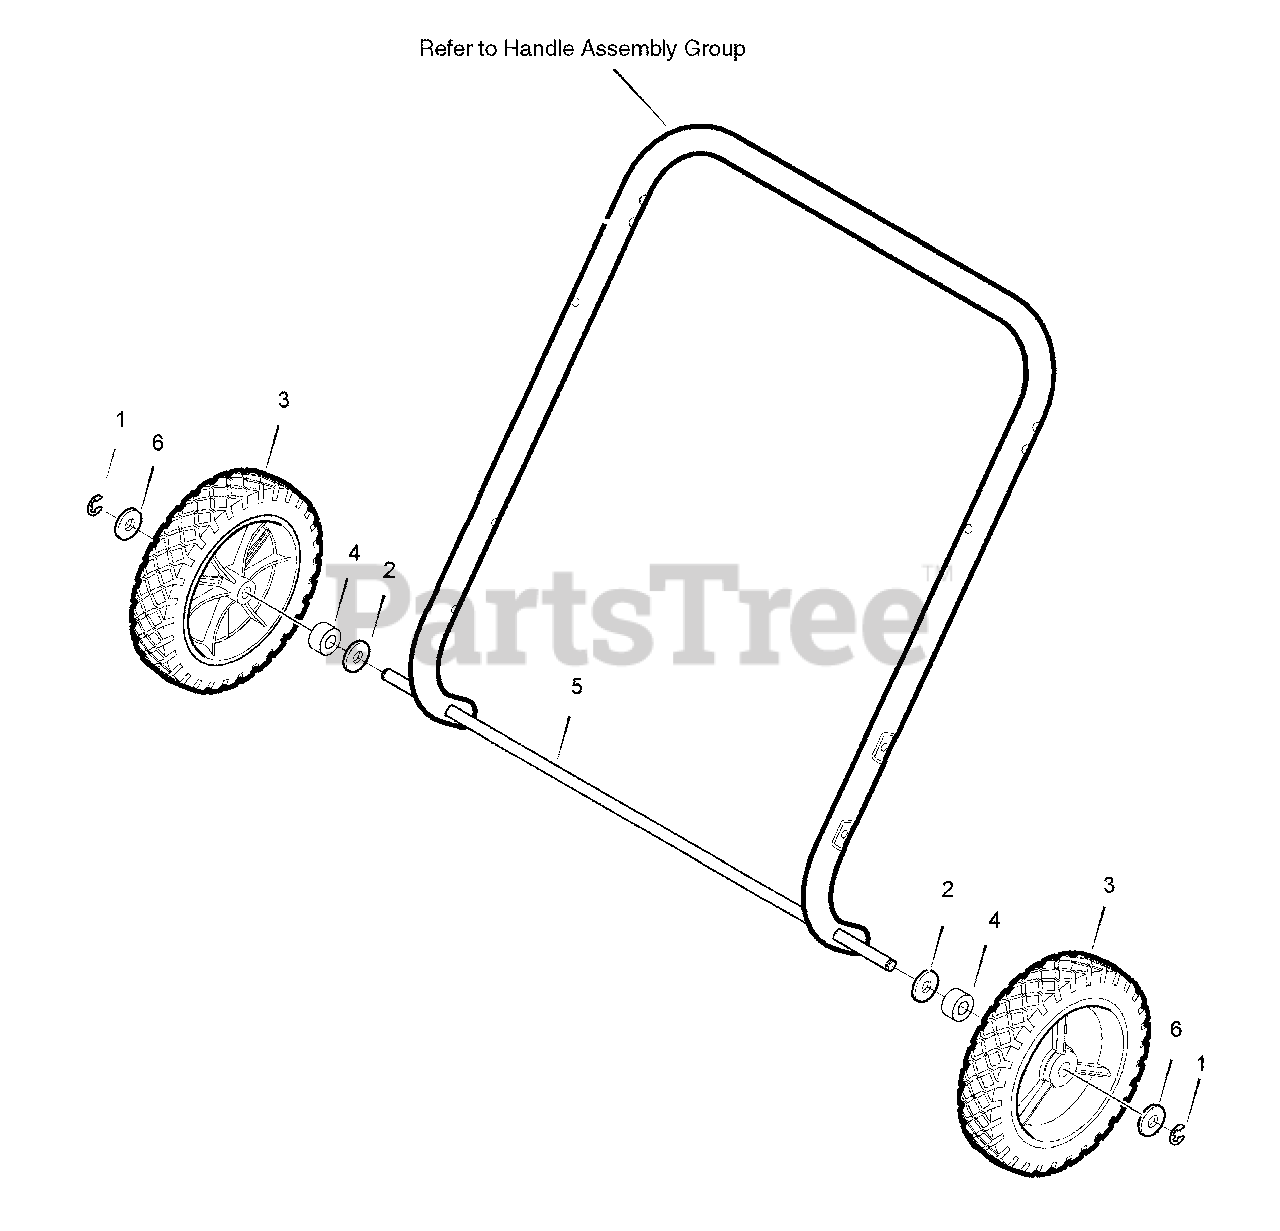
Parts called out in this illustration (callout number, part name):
1	RETAINER, E-Ring
2	WASHER, Flat 13/32 x 13/16
3	WHEEL & TIRE 7" x 1.50"
4	SPACER, Sleeve 13/32 x 5/8
5	Rod, Axle
6	WASHER, Flat - 25/64 x 1.00 x 1/8
